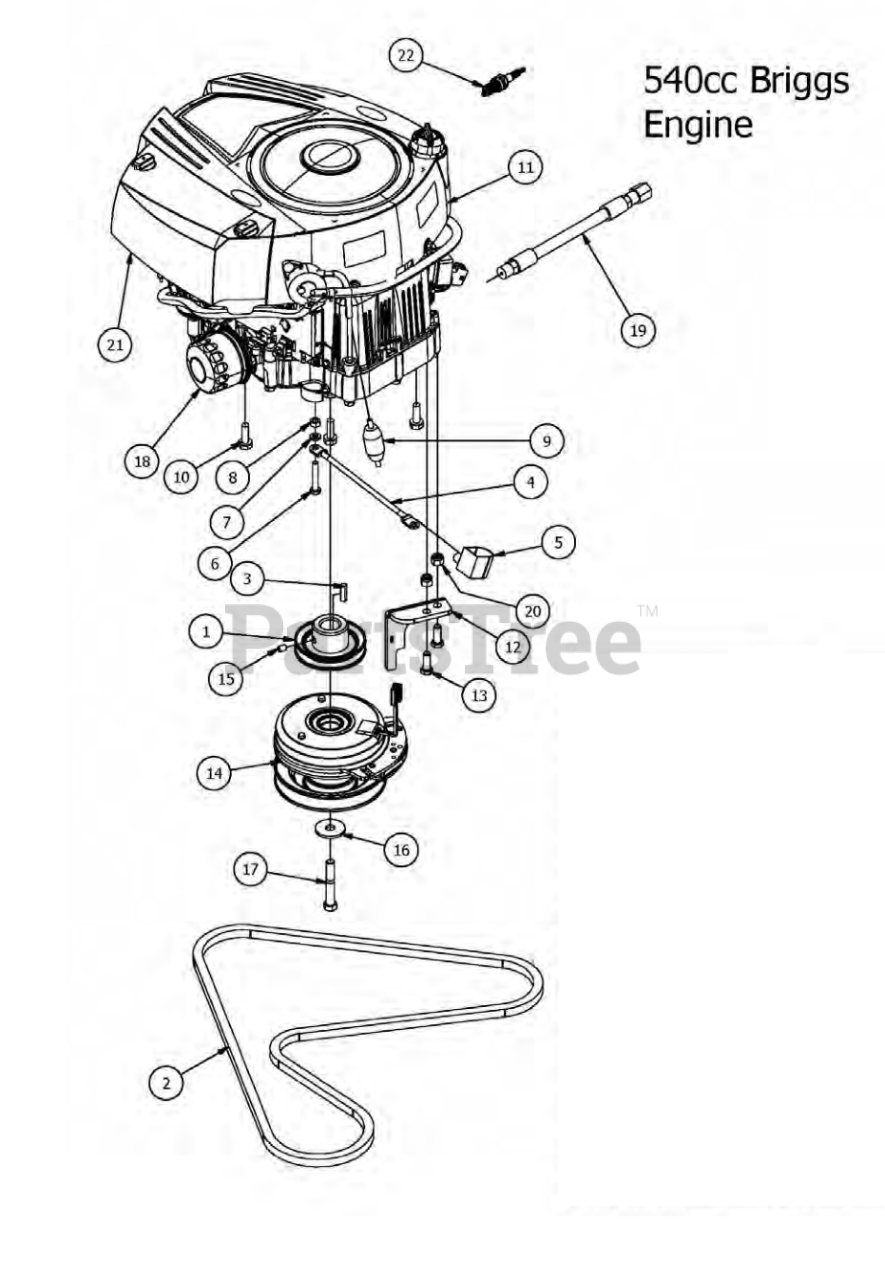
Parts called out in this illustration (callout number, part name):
1	3-3/4" Motor Pulley
3	1/4" x 1" Key
4	Ground Cable
5	Black Boot For Ground Cable
6	5/16" x 1 3/4" Hex Bolt
7	5/16" Lock Washer
9	Universal Inline Fuel Filter
10	3/8 x 1 1/8 bolt
11	540cc Briggs Intek Engine-MZ
12	Warner Clutch A-R Bracket
13	3/8" x 1" Hex Bolt
14	Clutch 2015 Magnum/MZ
15	3/8" Set Screw
16	1/2 Belleville Washer
17	7/16" x 4" Fine Thread Bolt
18	Briggs Oil Filter
19	Oil drain Hose
20	3/8 Nylock Nut
21	Air Filter
22	Spark Plug
